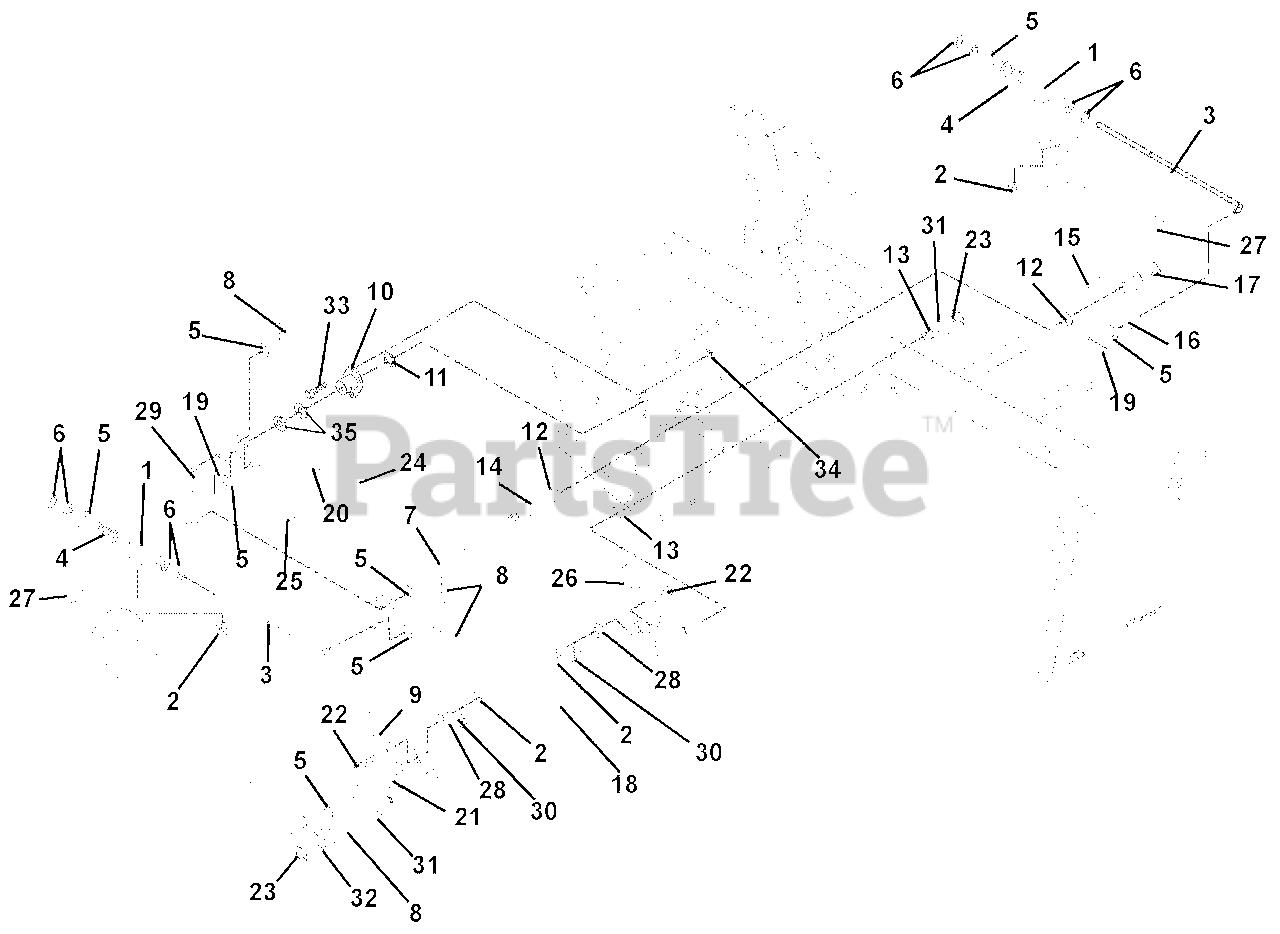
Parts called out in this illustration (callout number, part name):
1	PIN, PIVOT/TRUNNION
2	@NUT-LK-CTR .31-18 YWZC
3	PTO LINK ROD, PRO-150
4	SG-COMP .142 X .710 X 2.00
5	@WSHR-FL-STL.406X.812X.065 YWZ
6	@NUT-HEX .38-16 YWZC
7	WMT, BRAKE CROSS SHAFT
8	PIN-HAIR, ENDRIES #25 YWZC
9	SLIDE, INTERLOCKING BRAKE
10	BUSHING, FLANGED
11	RG-RTNG-EXT .625X.050
12	BSHG-FLG .762X1.0X.580X1.48 NY
13	BSHG-FLG .515X.750X.745X1.00NY
14	BSHG-SLV .750X1.000X.750
15	KEY-WDRF .19X.75 HRD #9
16	WMT, BRAKE ARM
17	RG-RTNG-EXT .689X.078
18	WMT, MECHANICAL BRAKE
19	@PIN-CTR .09X.75 EXTPRSQCT YWZ
20	WMT, BRAKE ACTUATING
21	KEY-WDRF .13X.63 HRD#5
22	@BLT-RDHDSQNK .31-18X1.25 G5YZ
23	RG-RTNG-EXT .500X.050 (SNAP)
24	KNOB-STEERING LOCK
25	LINKAGE, BRAKE ACTUATING
26	INTERLOCK, SAFETY SWITCH
27	PAD SET, DISK BRAKE
28	@NUT-LK-TOP-FLG .31-18 YWZC
29	LINKAGE, BRAKE ACTUATING
30	SG-TENS .063X.44X1.56
31	WSHR-FL-STL .505X1.00X.062YWZC
32	WMT, PARKING BRAKE HUB
33	@BLT-HEX .31-18X.75 GR5 YWZC
34	@NUT-LK-TOP-FLG .31-18 YWZC
35	WSHR-FL-STL .630X1.250X.062 YZ
